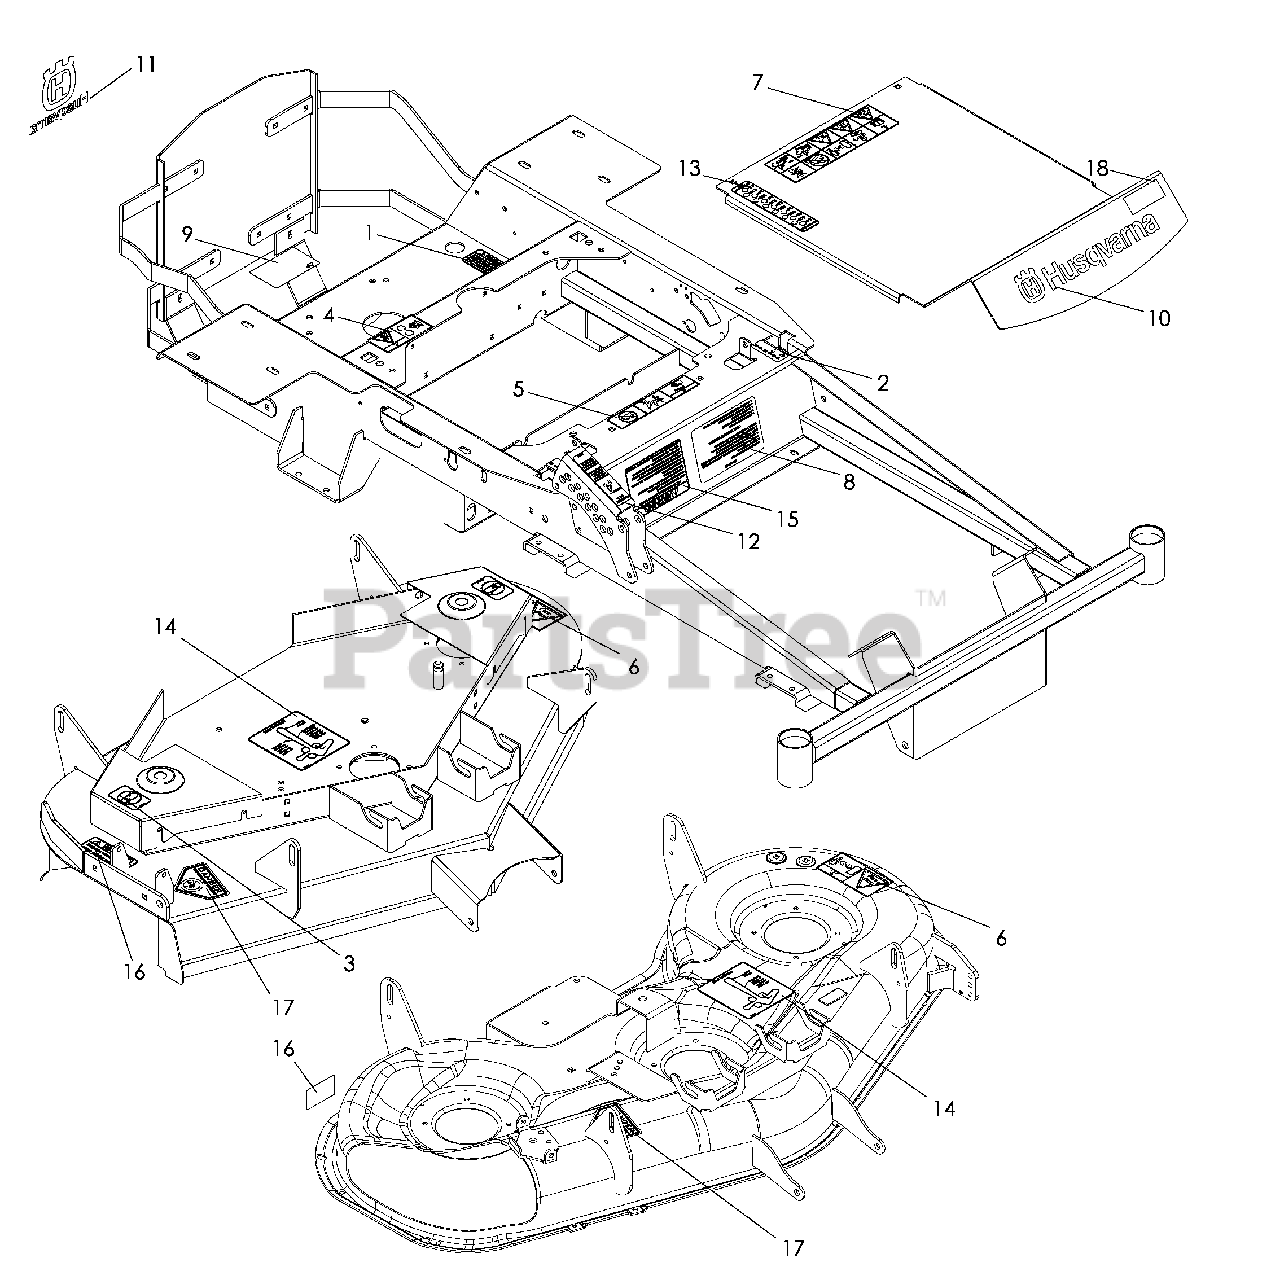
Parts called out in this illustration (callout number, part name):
1	DECAL, PROP 65
2	DECAL, MOTION CONTROL
3	DECAL, NO STEP
4	DECAL, DANGER BELT
5	DECAL, BATTERY WARNING
6	DECAL, SEVERING
7	DECAL, WARNING
8	DECAL, START
9	DECAL, DO NOT TOW
10	DECAL, HUSQVARNA
11	DECAL, CROWN
12	DECAL, TRNSPORT RELEASE
13	DECAL, HEIGHT ADJSTMENT
14	DECAL, BELT ROUTING
15	DECAL, WARNING
16	DECAL, CAUTION
17	DECAL, WARNING
18	DECAL, EZ4220
19	DECAL, EZ4624
20	DECAL, EZ4824
